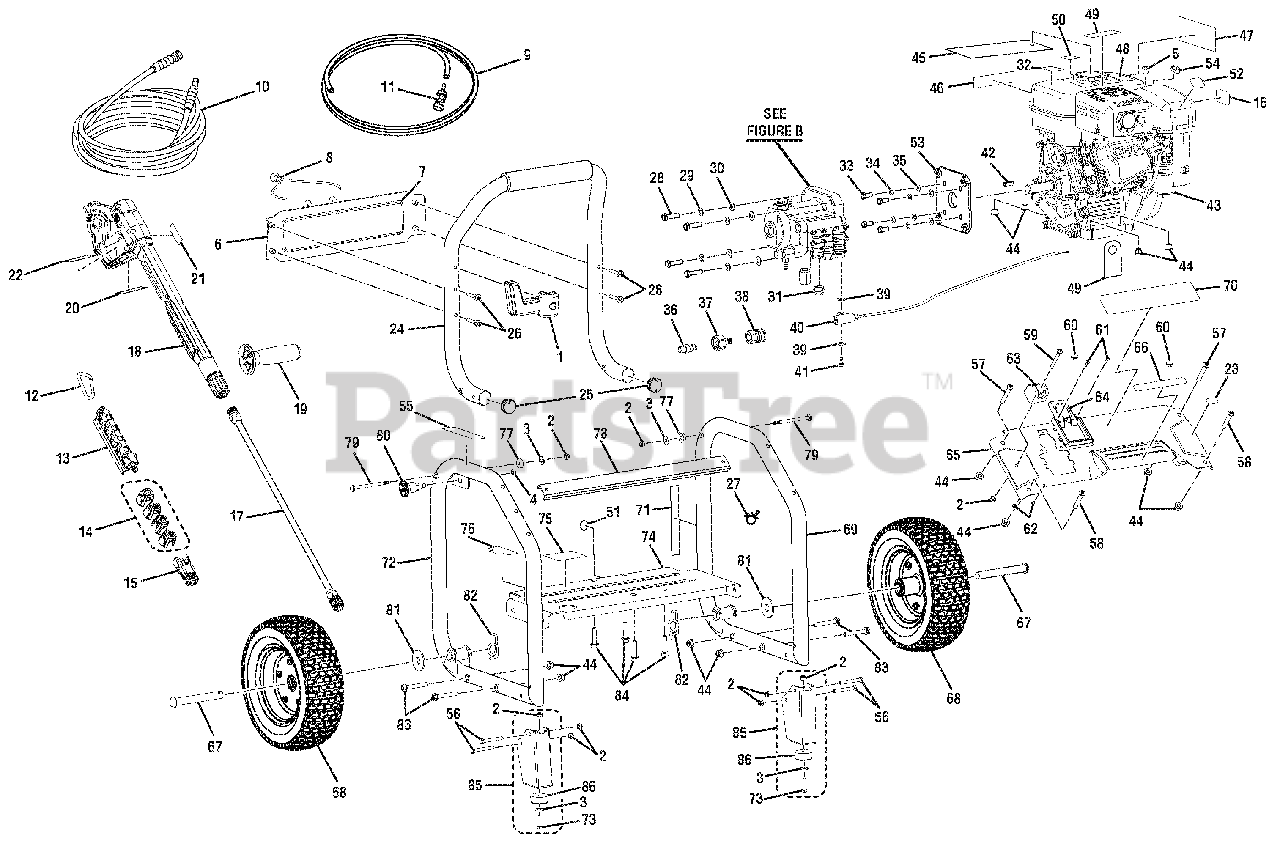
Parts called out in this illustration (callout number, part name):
1	Wand Holder Assembly
2	Lock Nut (1/4-20)
3	Washer (1/4 in.)
4	Lock Nut (1/2-20)
5	Swivel Bushing
6	Logo Plate
7	Performance Label
8	Bungee Cord and Bead Assembly
9	Injection Hose
10	High Pressure Hose (30 ft.)
11	Injection Hose Filter
12	Spring Clip
13	Storage Holder
14	Nozzle Kit
15	Soap Blaster Nozzle
16	Squeeze Trigger Label
17	Spray Wand
18	Trigger Handle Assembly (Inc. Key Nos. 19-22)
19	Auxiliary Handle Assembly
20	Trigger Guard Warning Label (French/Spanish)
21	Trigger Guard Warning Label (English)
22	Max Pressure Label
23	Idle Control Label
24	Handle Assembly (Inc. Key No. 25)
25	Handle Tube Cap
26	Bolt (1/4 x 42 mm, Pan Hd.)
27	Cable Clamp
28	Bolt (3/8-16 x 1-3/8 in., Hex Hd.)
29	Lock Washer (3/8 in.)
30	Washer (3/8 in.)
31	Threaded Valve Plug
32	Do Not Mix Label
33	Bolt (5/16-24 x 3/4 in., Hex Hd.)
34	Lock Washer (5/16 in.)
35	Washer (5/16 in.)
36	Thermal Release Valve
37	Garden Hose Coupler w/Filter
38	Quick Disconnect (Female)
40	Throttle Control Assembly
41	Throttle Control Bolt (Special)
42	Output Shaft Key (27 mm)
43	SP210 HORI. ENGINE (CARB, GV80993, 2012) (Parts available at your local Subaru dealer)
44	Lock Nut (M8 x 1.25 mm)
45	Hang Tag (Engine)
46	Add Lubricant Label
47	Combustion Warning Label
48	Danger Label (English)
49	Oil Dipstick Hang Tag
50	E-85 Label
51	Check Oil Label
52	Hot Muffler Label
53	Pump Flange
54	Cable Clamp
55	Handle Release Label
56	Bolt (1/4-20 x 52 mm, Hex Hd.)
57	Bolt (M8 x 50 mm, Hex Soc. Hd.)
58	Bolt (M8 x 46 mm, Hex Soc. Hd.)
59	Screw (1/4-20 x 2.1 in., T30, Torx Hd.)
60	Bumper Handle
61	Screw (M4 x 12 mm, Hex Button Hd.)
62	Lock Nut (M4)
63	Wand Holder
64	Trigger Handle Storage
65	Face Plate
66	Hot Surface Label
68	Wheel (D12 in. x 3 in.)
69	Left Frame
70	Logo Label
71	Quick Start Label (Engine)
72	Right Frame Assembly
73	Bolt (1/4-20 x 1 in.)
74	Engine Plate
75	Data Label (GV80993)
76	Quick Start Label (Pump)
77	Washer (OD20 x ID8 x 4.5t)
79	Connector Pin (1/4 in.)
80	Handle Knob
81	Washer (5/8 in.)
82	Hitch Pin
83	Bolt (M8 x 55 mm, Hex Hd.)
84	Bolt (M8 x 45 mm, Hex Hd.)
85	Foot Assembly (Inc. Key Nos. 2-3 and 86-87)
86	Wear Pad
